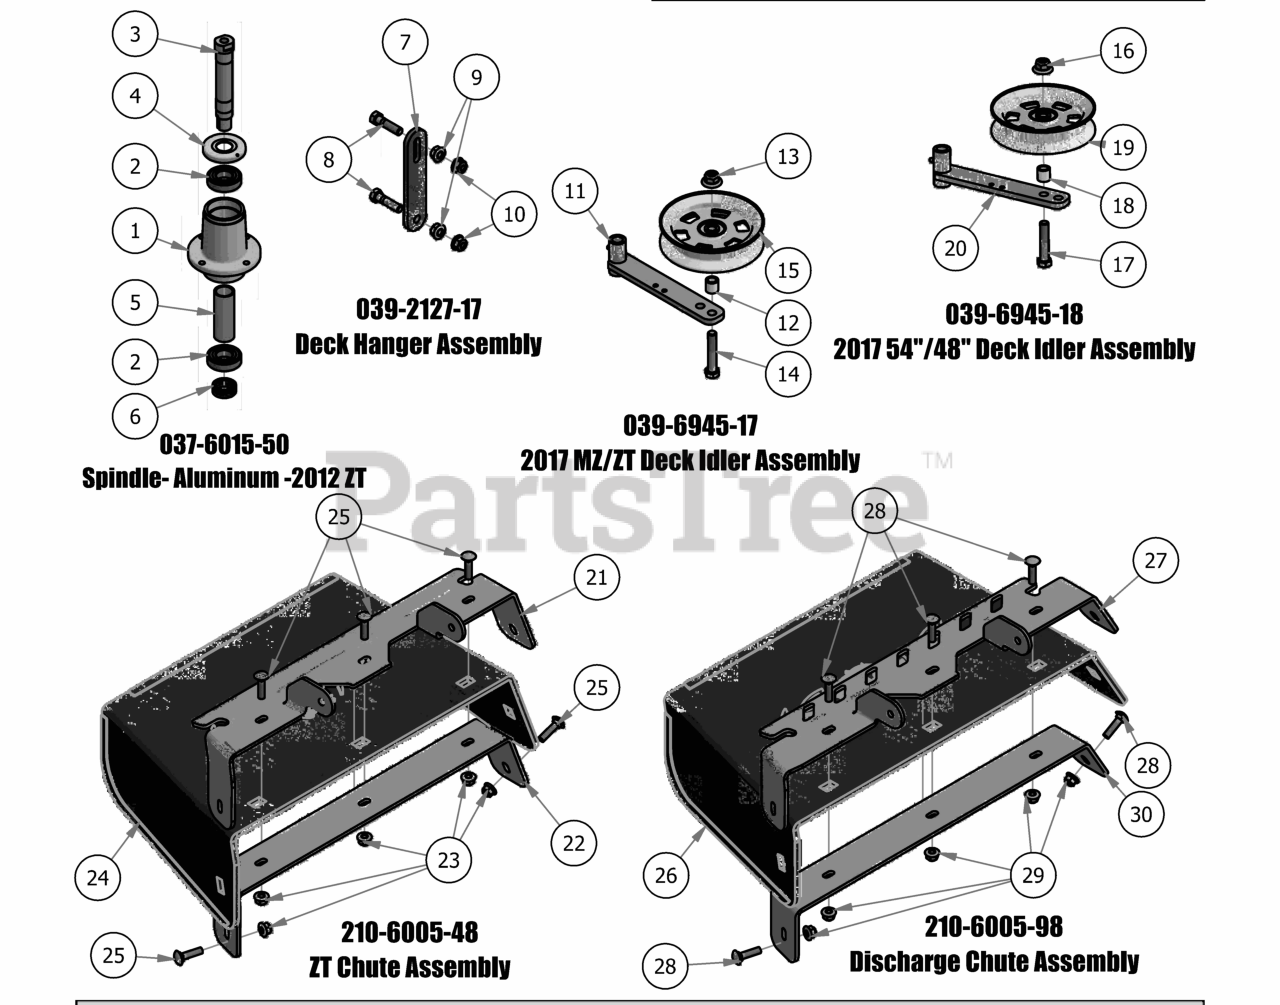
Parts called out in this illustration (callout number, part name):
1	Aluminum Spindle Housing -2010
2	Spindle Bearing, 2004 and up
3	Short Spindle Shaft w/Locking
4	Dust Cover
5	Tube Spacer for Spindle Shaft
6	Collar Spacer - Top of Spindle
7	2017 MZ/ZT Deck Hanger
8	3/8" x 1 1/2" Hex Bolt
9	3/8" Flange Nut
10	3/8" Nylock Flange Nut
11	Deck Idler
12	Spacer 3/4 OD x 1/2 ID x 3\4 Length
13	1/2-13 Nylon Flange Nut
14	1/2" x 2 3/4" Hex Bolt
15	5" Idler Pully
16	1/2-13 Nylon Flange Nut
17	1/2" x 2 1/2" Hex Bolt
18	Spacer 3/4 OD x 1/2 ID x 3\4 Length
19	5" Idler Pully
20	Deck Idler
21	Discharge Upper Chute Bracket
22	Discharge Lower Chute Bracket
23	5/16" Nylon Flange Nut
24	Rubber Discharge Chute
25	5/16" x 1 1/4" Carriage Bolt
26	Rubber Discharge Chute
27	60" Discharge Chute Upper Hanger
28	5/16" x 1 1/4" Carriage Bolt
29	5/16" Nylon Flange Nut
30	60" Discharge Lower Bracket
